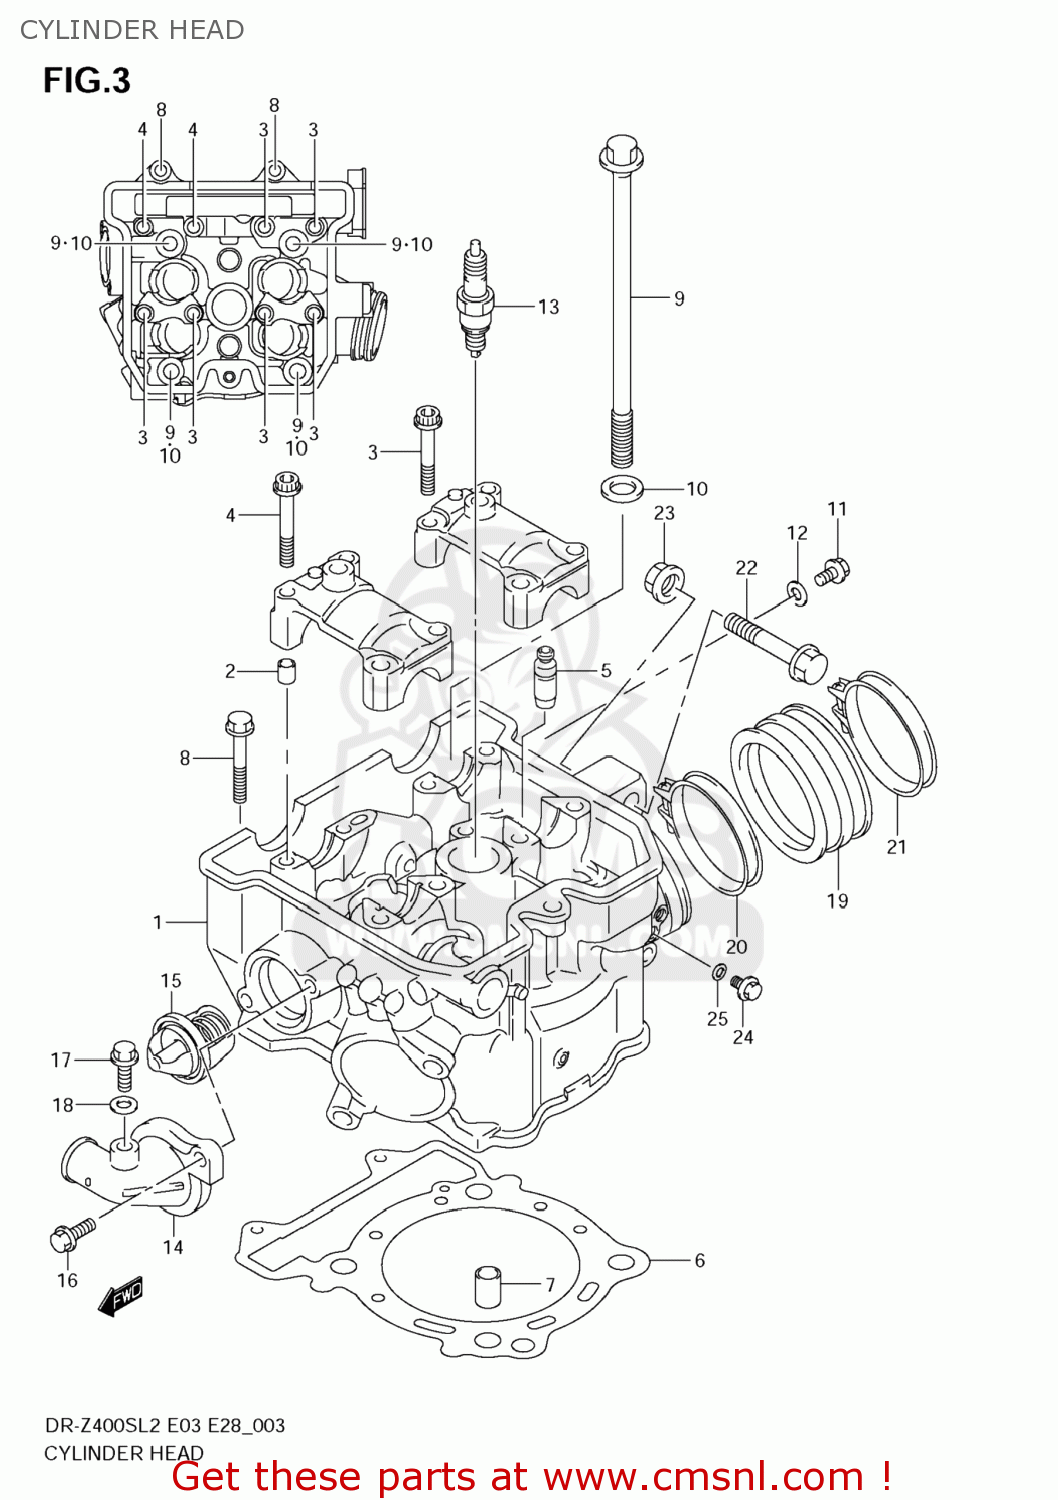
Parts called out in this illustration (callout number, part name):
1	HEAD ASSY,CYLINDER
2	PIN(6.2X8X11)
3	BOLT
4	BOLT
5	GUIDE,VALVE
6	GASKET,CYLINDER HEAD (NAS)
7	PIN
8	BOLT(6X39)
9	BOLT(10X175)
10	WASHER(10.5X19X2)
11	BOLT
12	GASKET(5.8X13X1.2) (NAS)
13	PLUG,SPARK(CR8E)
14	COVER,THERMOSTAT
15	THERMOSTAT,WATER
16	BOLT
17	UNION BOLT,AIR VENT
18	GASKET(6.4X11.5X0.8) (NAS)
19	PIPE,INTAKE
20	CLAMP
21	CLAMP
22	BOLT(10X50)
23	NUT
24	BOLT(8X9.5)
25	GASKET(8.2X14X1) (NAS)
